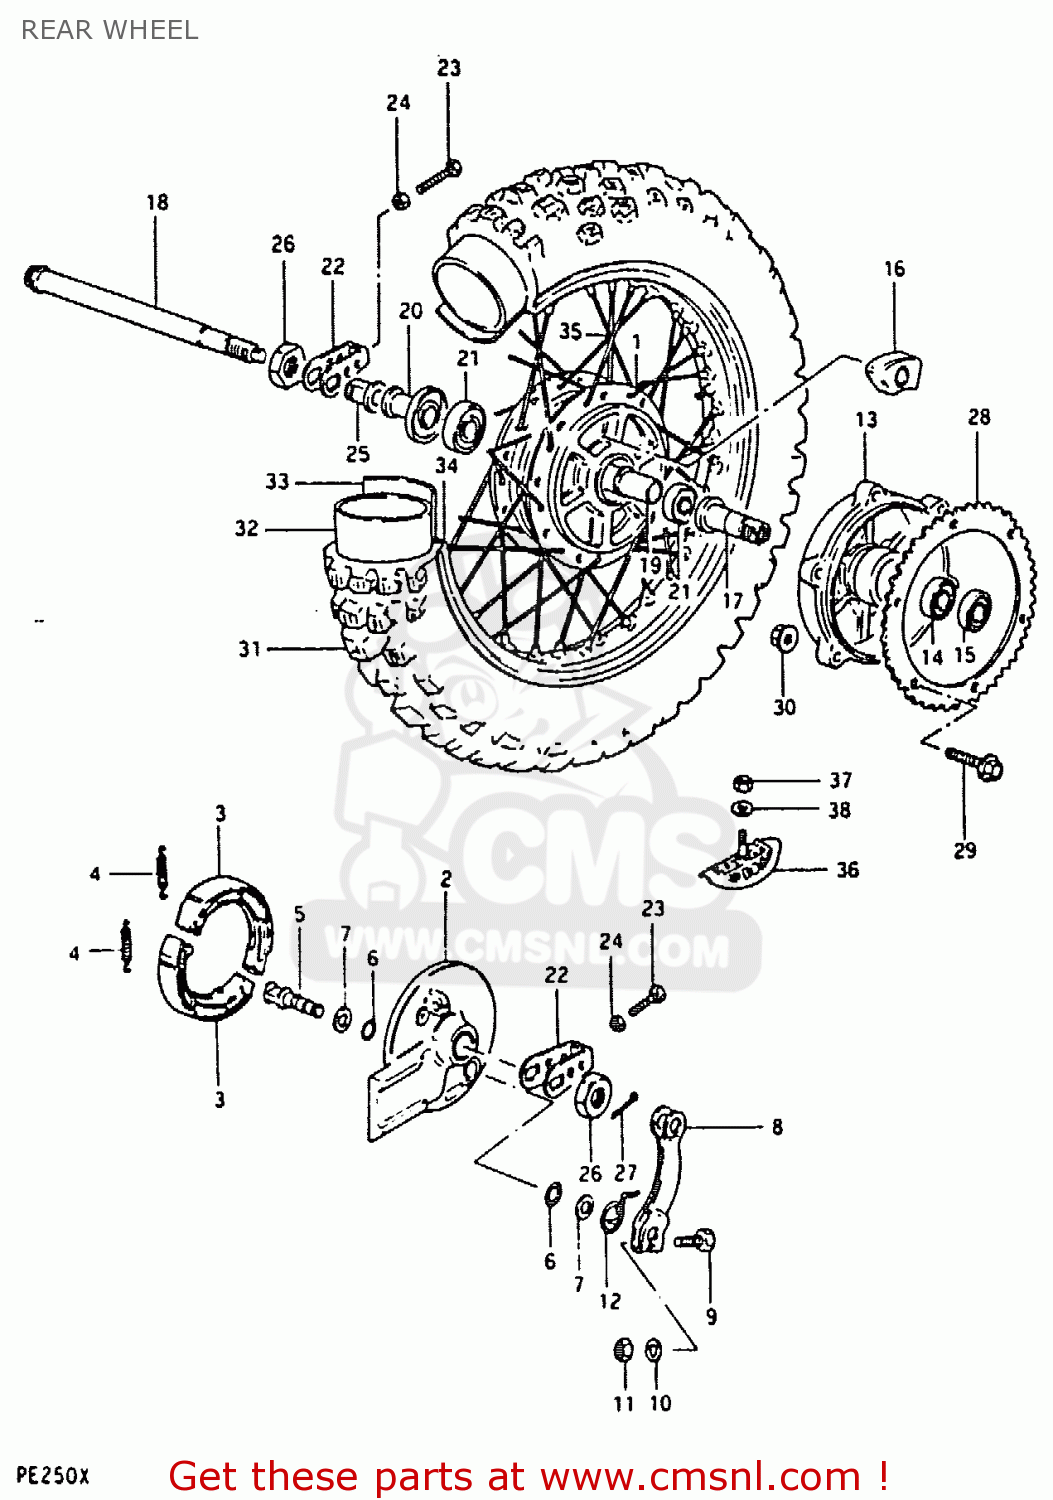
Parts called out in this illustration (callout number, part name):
1	HUB,REAR WHEEL
2	PANEL,REAR HUB
3	SHOE,BRAKE
4	SPRING
5	CAM,FRONT BRAKE
6	O-RING,BOSS
7	WASHER (15X24X1.6)
8	LEVER,REAR BRAKE CAM
9	BOLT
10	WASHER
11	NUT
12	SPRING
13	DRUM ASSEMBLY,REAR BRAKE
14	BEARING
15	BEARING
16	ABSORBER,RR HUB SHOCK
17	SHAFT,REAR BRAKE DRUM
18	AXLE,REAR
19	SPACER,REAR HUB BEARING
20	SPACER,REAR AXLE
21	BEARING
22	ADJUSTER,CHAIN
23	BOLT
24	NUT
25	SPACER,CHAIN ADJUSTER
26	NUT
27	PIN 30X20
28	SPROCKET,REAR
29	BOLT(8X30)
30	NUT
31	TIRE
32	TUBE,INNER
33	PROTECTOR,WHEEL,INNER
34	RIM,REAR WHEEL
35	SPOKE SET,REAR
36	STOPPER,BEAD
37	NUT
38	WASHER
